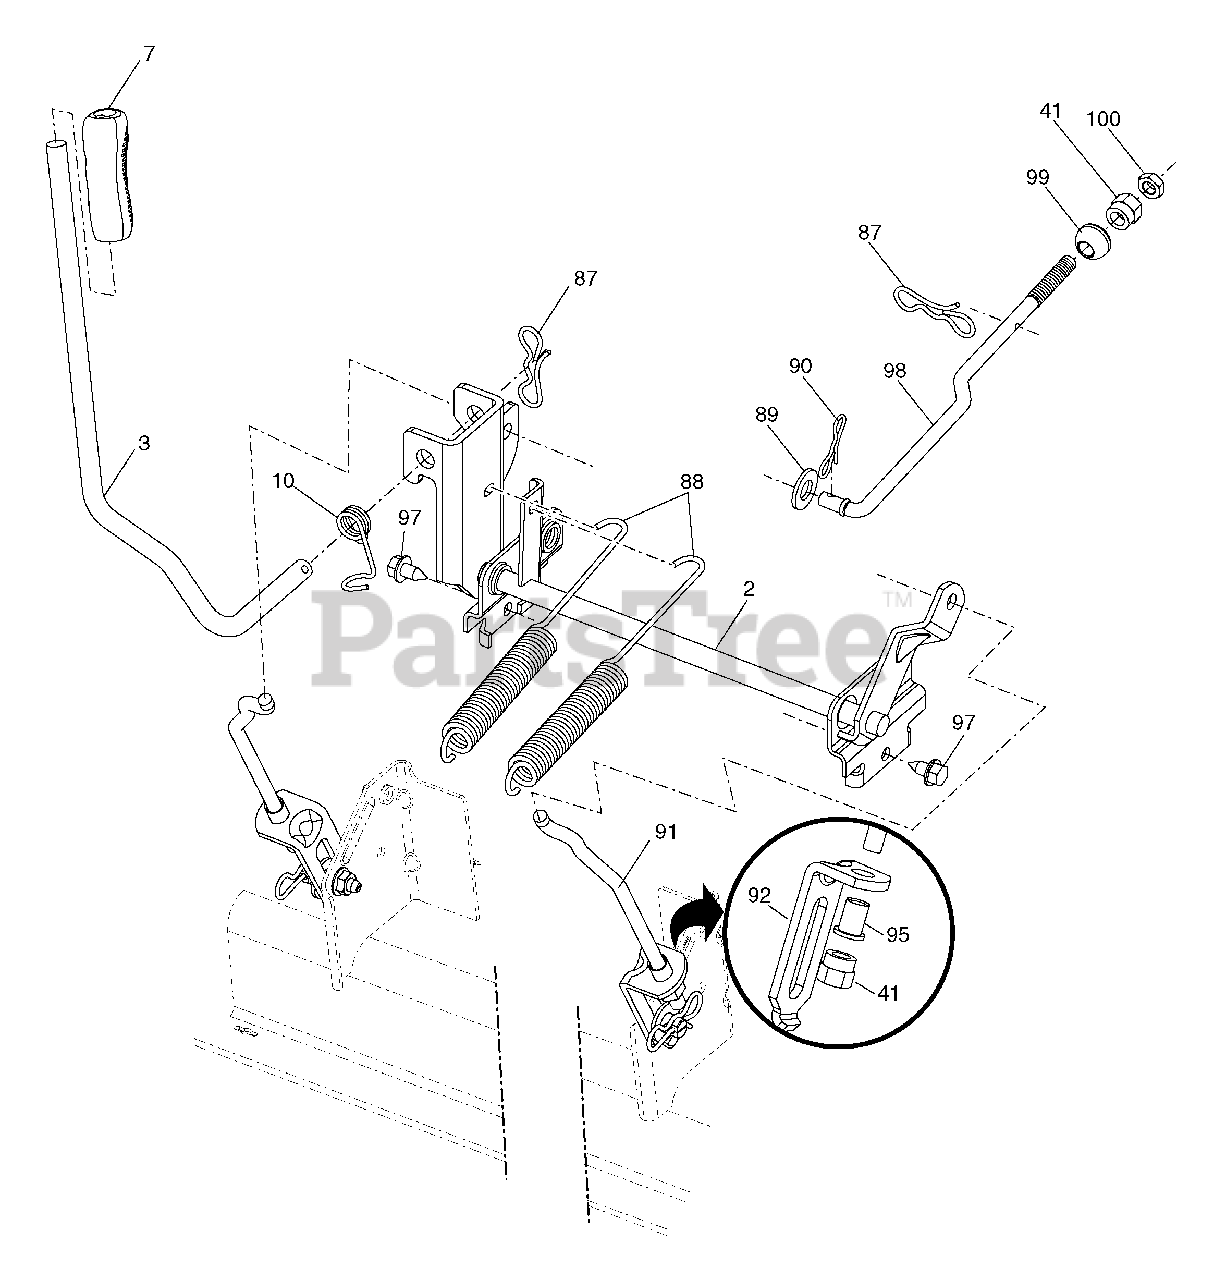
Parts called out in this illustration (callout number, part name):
2	Shaft Asm., Lift
3	Lever Asm., Lift Rh
7	Grip, Lever
10	Spring Torsion
41	Nut, 7/16-20
87	Pin Cotter 7/16 Bow Tie Lock
88	Spring Lift Assist
89	Washer Clear Zinc
90	Pin Cotter 5/16 Bow Tie Lock
91	Link Lift Susp Mower Rear
92	Bracket Connect Link Lift
95	Bushing Alignment Link Lift
97	Screw 3/8-16 x .75 Smgml Tap/R.Z
98	Link Lift Susp. Front Mower
99	Bushing Spherical Susp Front
100	Nut Hex Jam ASF 7/16-20 unf
